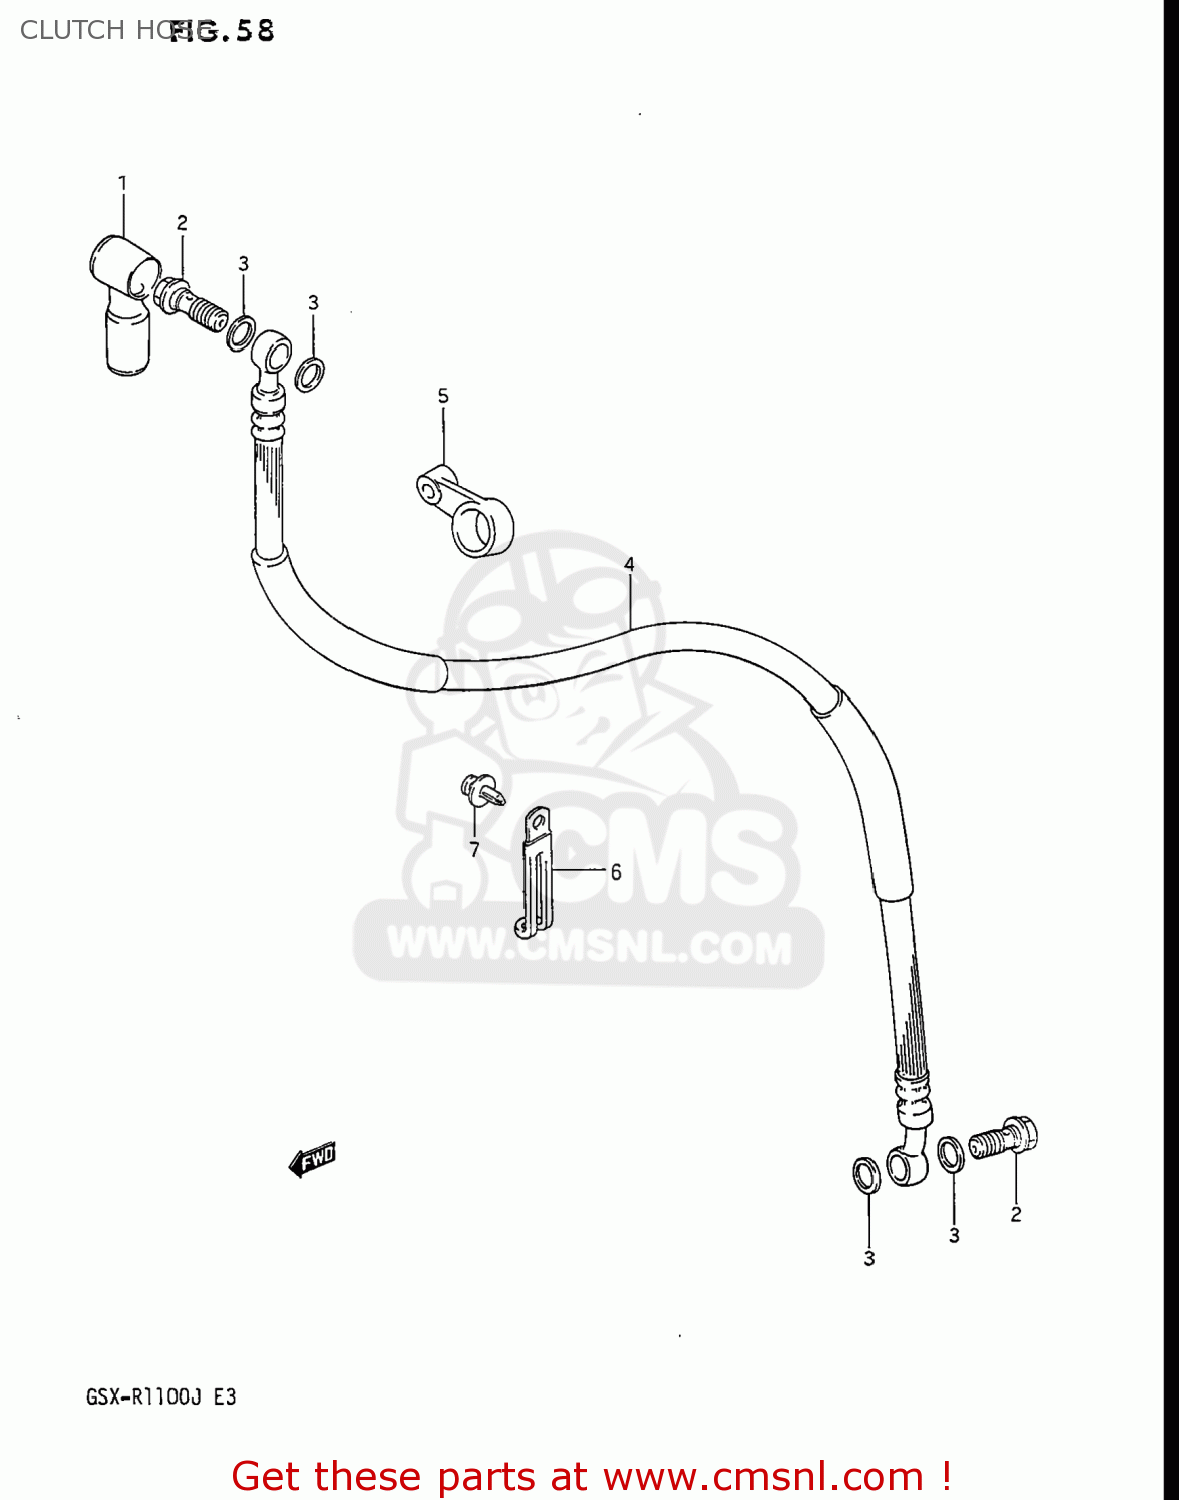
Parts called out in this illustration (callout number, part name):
1	BOOT,MASTER CYLINDER
2	BOLT UNION
3	WASHER(10X15X1.5)
4	HOSE,CLUTCH
5	CLAMP,CLUTCH HOSE NO.2
6	CLAMP
7	CLIP
